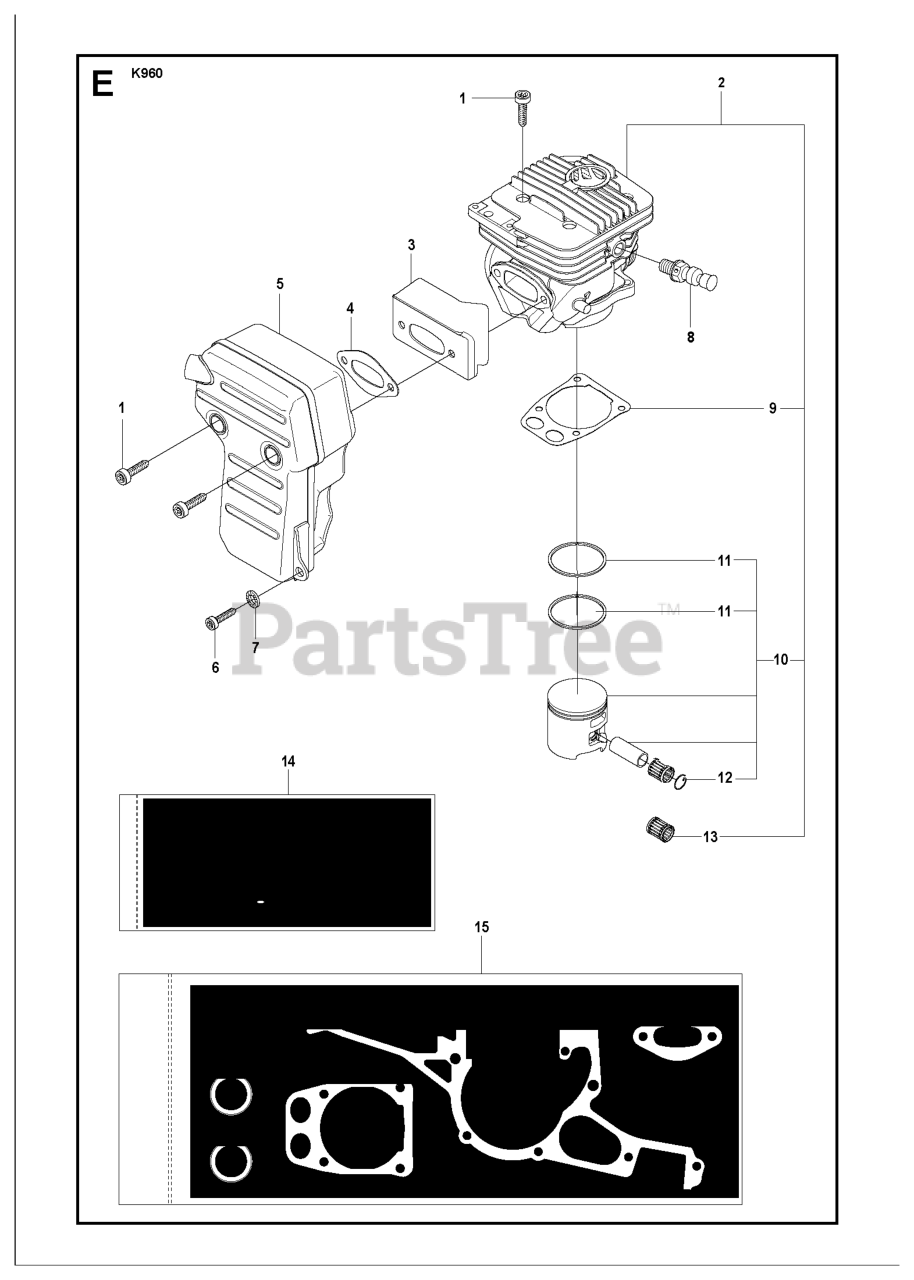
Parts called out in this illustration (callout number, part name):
2	RP CYLINDER ASSY
3	HEAT DEFLECTOR
4	GASKET MUFFLER
5	MUFFLER
7	DOUBLE WASHER
9	RP GASKET
11	PISTON RING
13	SUPPORT BUSHING
14	MUFFLER MOUNTING KIT K960
15	RP GASKET KIT
16	SEALING RING
17	RP GASKET
